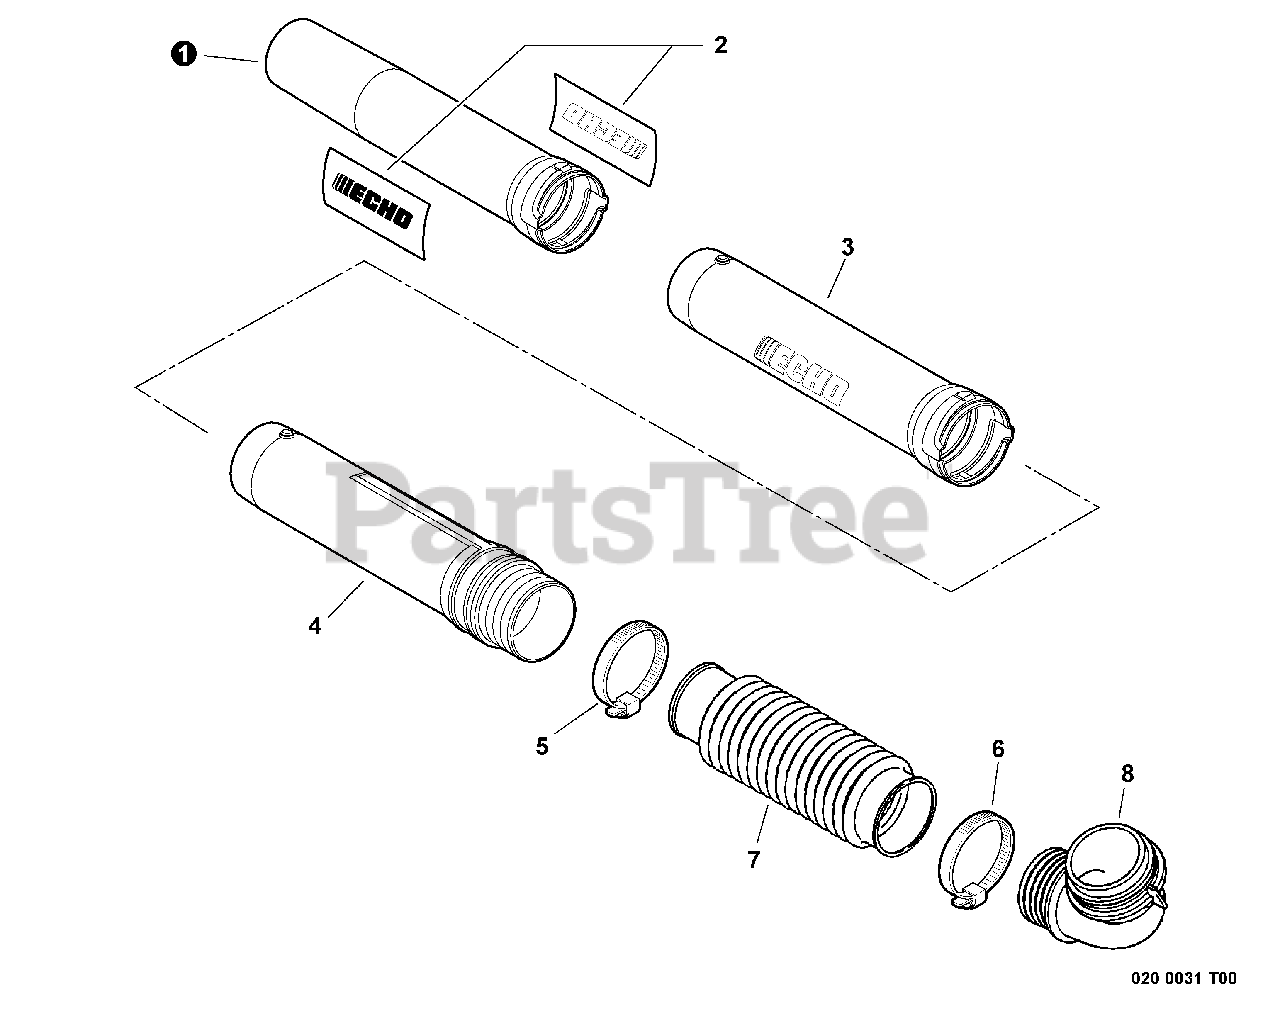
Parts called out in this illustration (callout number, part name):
1	TUBE, BLOWER - NOZZLE
2	LABEL - ECHO
3	TUBE, BLOWER - STRAIGHT
4	TUBE, BLOWER - SWIVEL
5	CLAMP, HOSE
6	CLAMP, HOSE
7	TUBE, BLOWER - FLEXIBLE
8	TUBE, BLOWER - ELBOW
